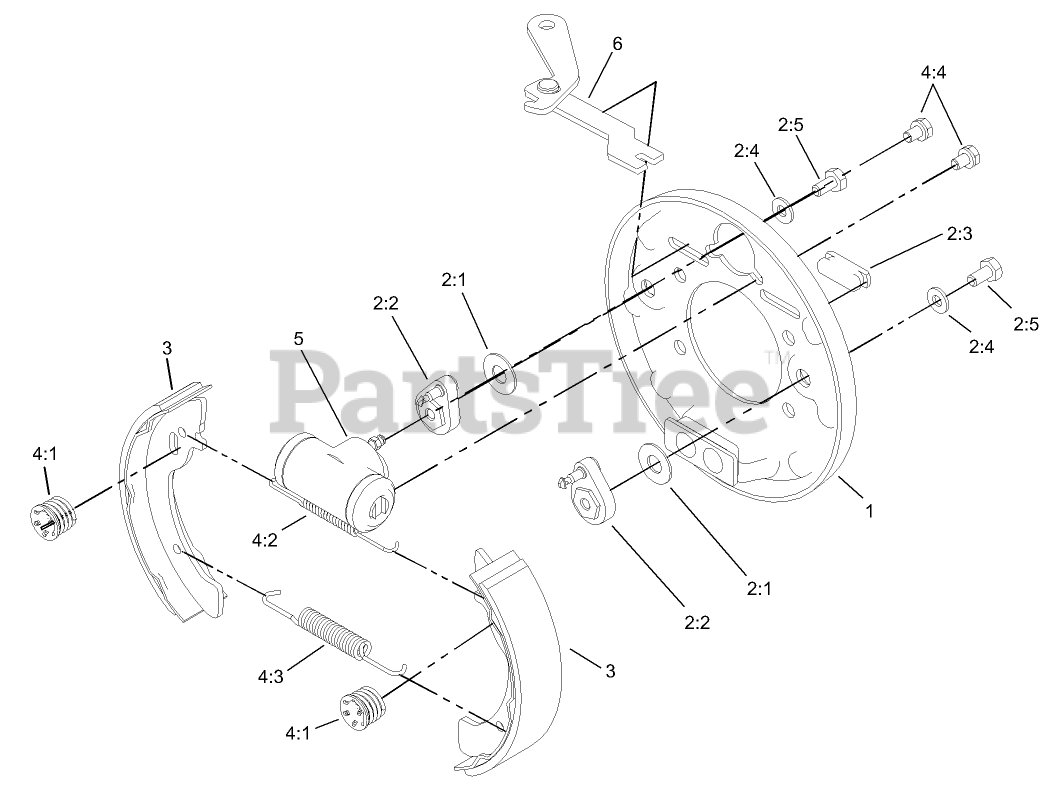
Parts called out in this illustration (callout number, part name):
1	BACKING PLATE ASM
2	ADJUSTER KIT
2:1	WASHER-BELLVILLE
2:2	ADJUSTER LEVER ASM
2:3	COVER-DUST
2:4	Washer
2:5	Bolt
3	SHOE AND LINING KIT
4	HARDWARE KIT
4:1	SHOE HOLD DOWN SPRING ASM
4:2	SPRING-UPPER
4:3	SPRING-LOWER
4:4	Loose Parts Package
5	WHEEL CYLINDER ASM
6	RH PARK BRAKE LEVER ASM
